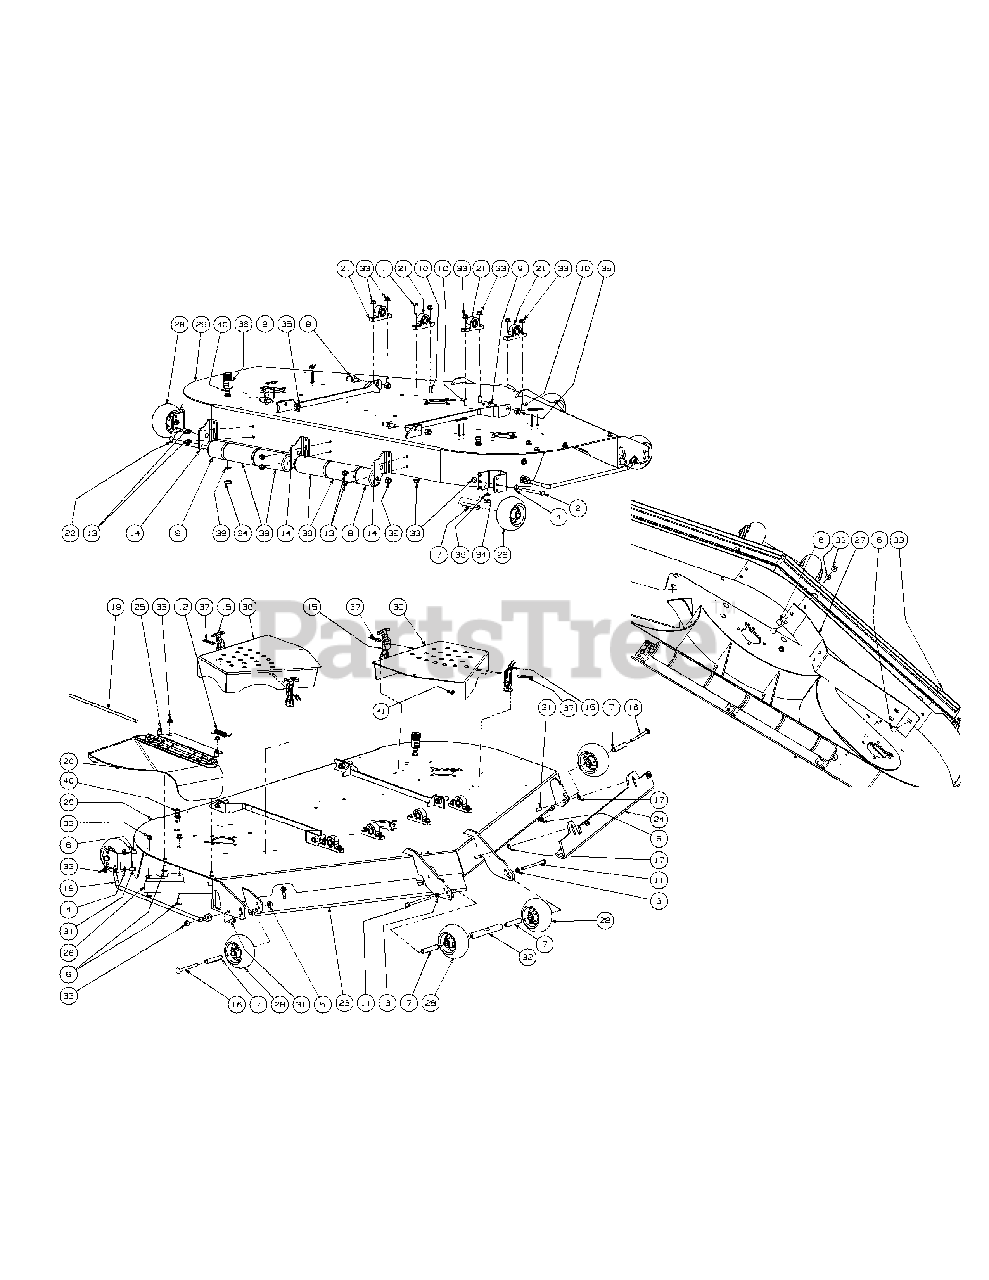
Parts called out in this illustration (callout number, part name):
1	Hex Cap Screw, 3/8-16, 1.25
2	Hex Cap Screw, 3/8-16, 4.00
3	Lock Washer, 3/8
4	Flat Washer, 3/8
5	Flange Lock Hex Nut, 3/8-16
6	Carriage Bolt, 3/8-16 x .75 Lg.
7	Wheel Spacer
8	Grass Catcher Roller
9	Pin, 5/8 Dia. x 1.2 Lg.
10	Carriage Screw, 3/8-16 x 1.25
11	Hex Cap Screw, 3/8-16 x 4.50
12	Torsion Spring, 0.4ID x 2.16Lg
13	Hex Index Washer Screw, 3/8-16, .5
14	Deck Roller Mount Bracket
15	T-Handle Latch Draw
16	Carriage Bolt, 3/8-16 x 4.00
17	Push Retainer
18	Finger Guard
19	Pin, .375 x 14.06
20	Chute Deflector
21	Pillow Block, Steel
22	J-Hook w/ Threaded Roller
23	Right Hand Front Adjustment Skirt
24	Left Hand Front Adjustment Skirt
25	Chute Deflector Bracket
27	Baffle, 72" Adjustment
28	Complete Wheel, 5.00 Dia.
29	72" Deck Assembly
30	Deck Belt Cover
31	Carriage Bolt, 3/8-16 x 1
32	Ball Wheel Mounting Shaft
33	Flange Lock Hex Nut, 3/8-16
34	Hex Nut, M16-1.5
35	Lock Nut, Nylon Insert, 1/2-13
36	Water Nozzle Adaptor
37	Phillips Head Screw, #10-32 x 1/2
38	Front Roller
39	Lock Washer, 17 x 23.8 x 1.95
40	Deck Water Nozzle
41	Lock Nut, Nylon Insert, #10-32
